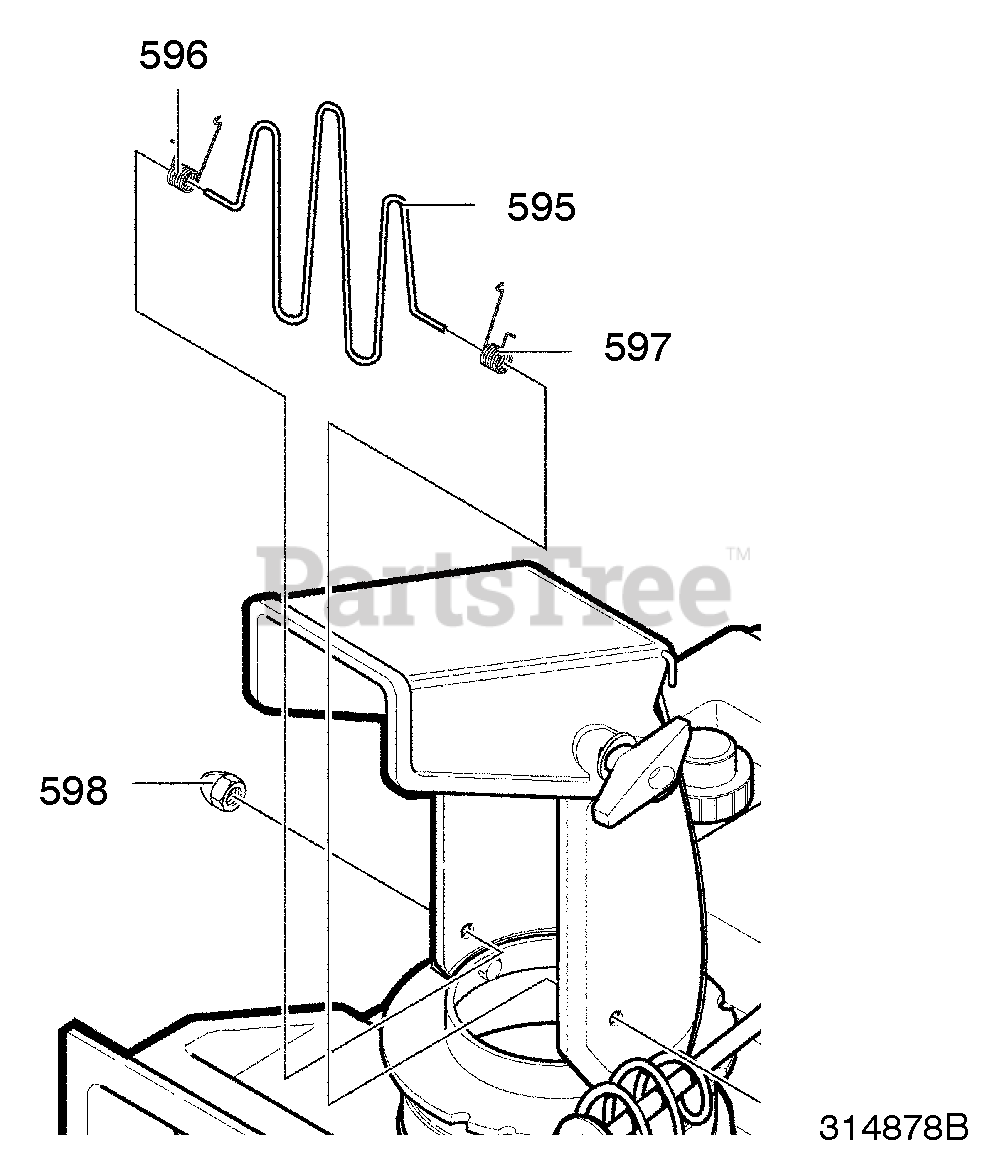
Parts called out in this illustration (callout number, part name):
595	GUARD, WIRE CHUTE
596	SPRING, TORSION
597	SPRING, TORSION
598	NUT, ACORN
